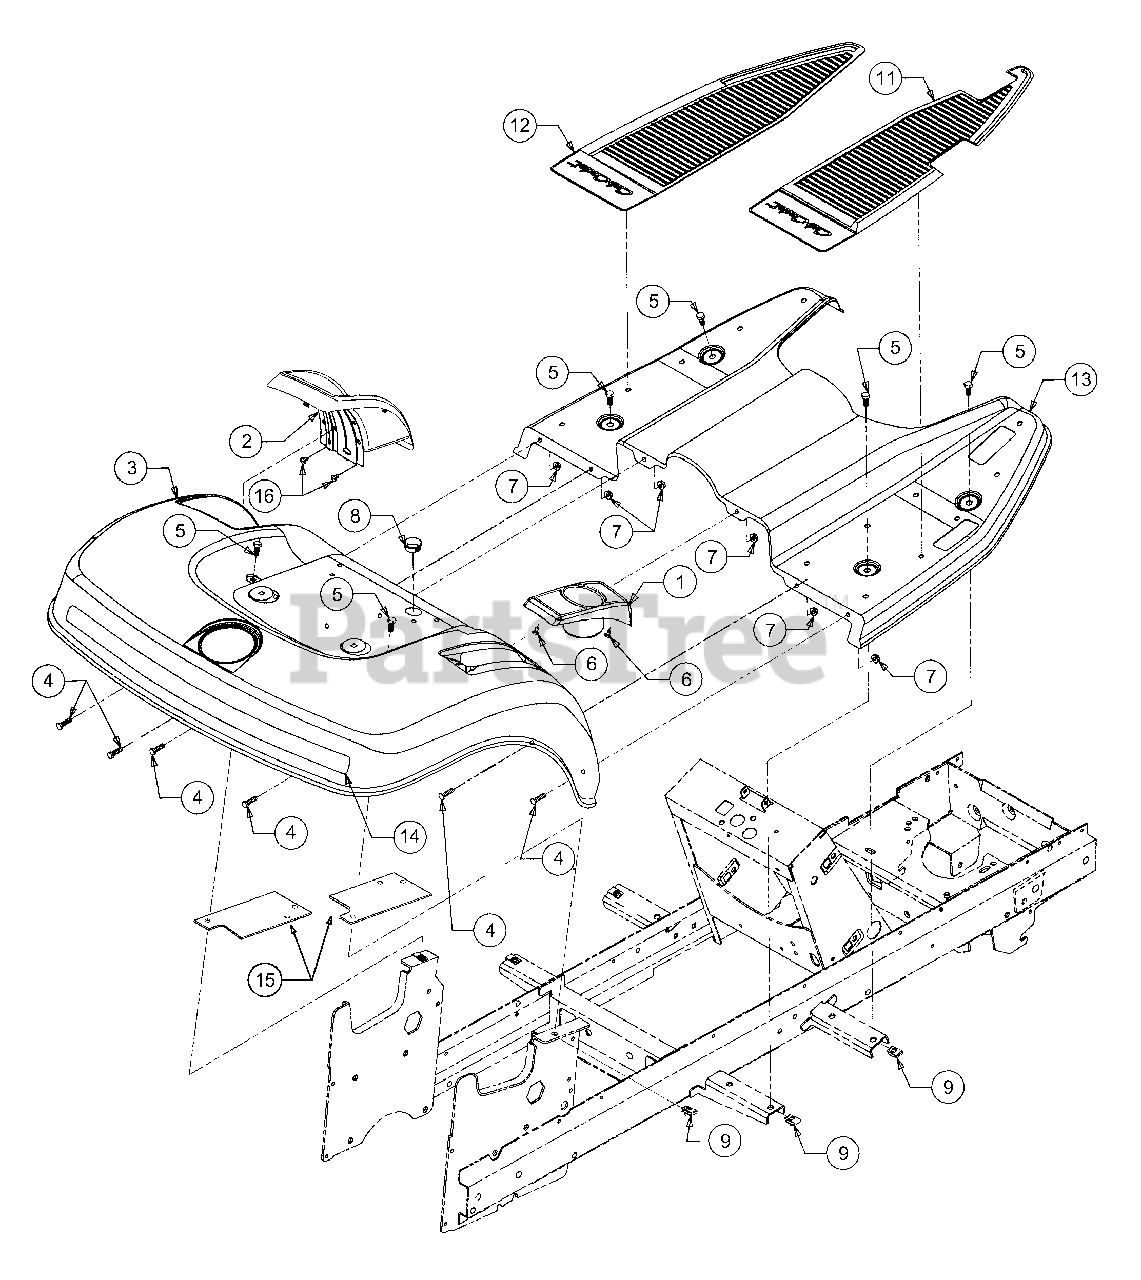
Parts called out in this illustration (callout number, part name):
1	Cup Holder
2	Cover, Implement Lift
4	Screw, Hex Cap, 1/4-20 x .62 GR5
5	Screw, Hex Wash Hd Tapp 5/16-18 x .750
6	Screw, Hex Tapp, #10 x .38 Lg
7	Nut, Hex Flange Lock, 1/4-20
8	Bushing, Snap, 7/8 ID
9	U-Nut, 5/16-18
11	Pad, RH Foot
12	Pad, LH Foot
14	Graphic, Rear Fender
